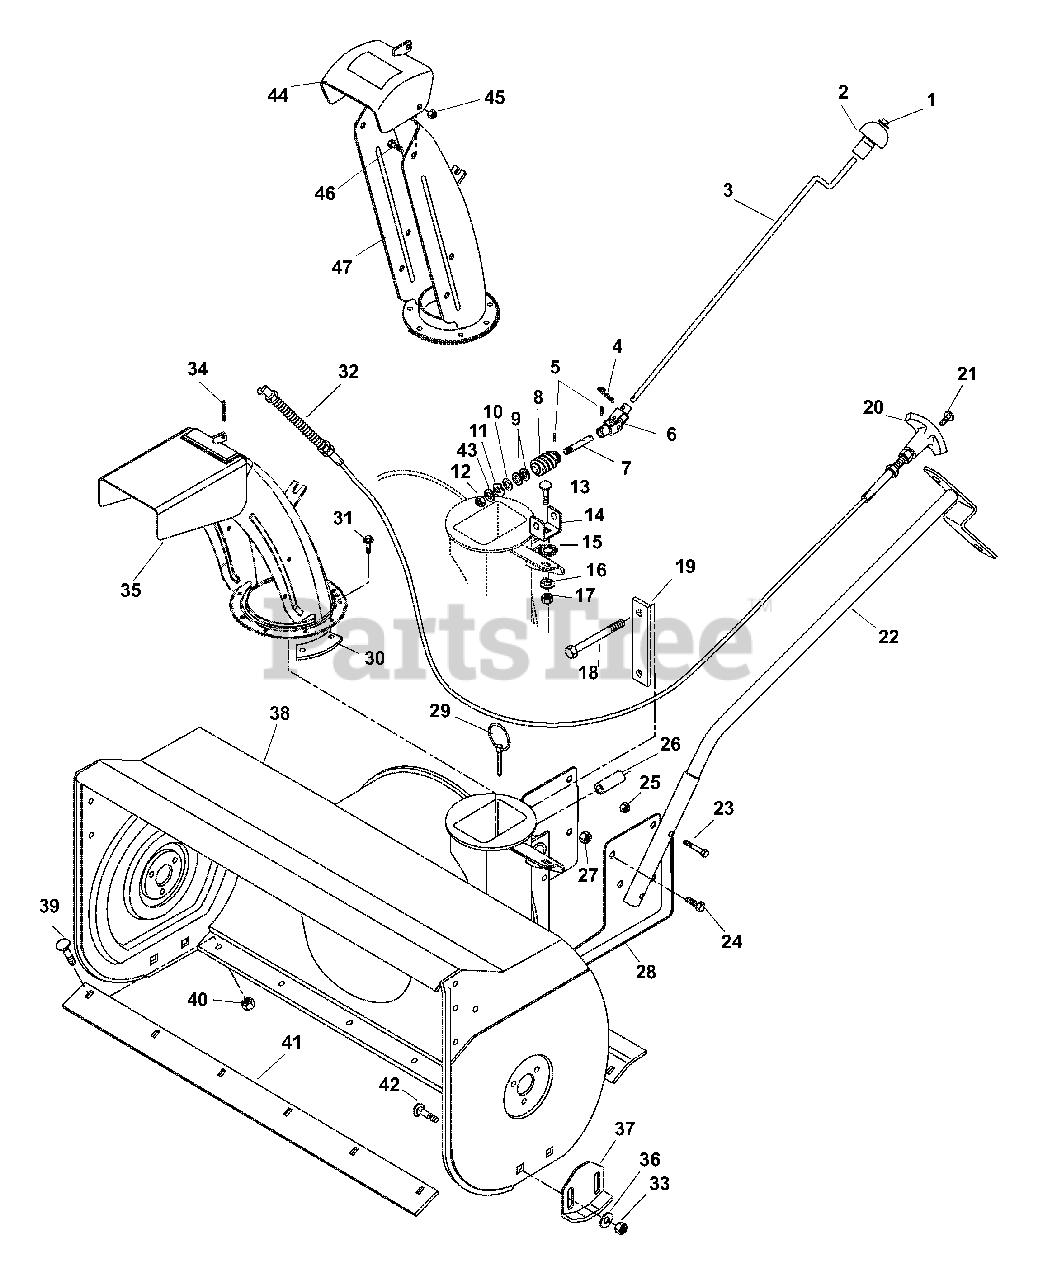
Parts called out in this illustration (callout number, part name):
1	Cap - 3/8" Rod
2	Knob
3	Crank Chute Control
4	Pin-Hair Internal .08 x .38 x 1.42
5	Pin-Roll .125 x .750
6	Universal Joint Assembly
7	Worm Shaft
8	Worm Gear Left Hand
9	Washer-Plastic .390 x .875 x .062
10	Washer-Flat-Steel .43 x 1.00 x .16
11	Wave Washer
12	Nut-Lock-Center .38-16
13	Bolt-Round Head Square Neck .31-18 x .75
14	Worm Clevis
15	Washer-Lock External .375 x .035
16	Washer-Lock .313 x .062
17	Nut-Hex .312-18 Grade 2
18	Bolt-Hex .50-13 x 4.50
19	Strap, Locking
20	Knob-Black
21	Screw-Machine 8-32 x .75
22	Crank Support
23	Bolt-Round Head Square Neck .31-18 x .75
24	Bolt-Hex .50-13 x 1.25 Grade 5
25	Nut-Locking Top .375-16
26	Bushing Sleeve .501 x 1.00 x 2.30
27	Nut-Locking-Nylon .50-13 Grade 5
28	Support Bracket
29	Pin-Self-Lock .25 x 1.00
30	Chute Clamp
31	Screw-Tapping 12-24 x .50
32	Control Cable
33	Nut-Locking .375-16
34	Pin-Cotter .09 x .75
35	Chute, Discharge with Cap-Krinkle Black
36	Washer-Flat-Steel .406 x .812 x .065
37	Runner-Skid Shoe
38	32" Sno-Thro Housing
39	Bolt-Round Head Square Neck .31-18 x .88
40	Nut-Locking .312-18
41	Scraper Blade, 32"
42	Bolt-Round Head Square Neck .38-16 x 1.0
43	Washer-Flat-Steel .406 x .812 x .065
44	Deflector with Decal
45	Nut-Locking-Center .38-16
46	Bolt-Hex .38-16X.75 Grade 5
47	Discharge Chute
